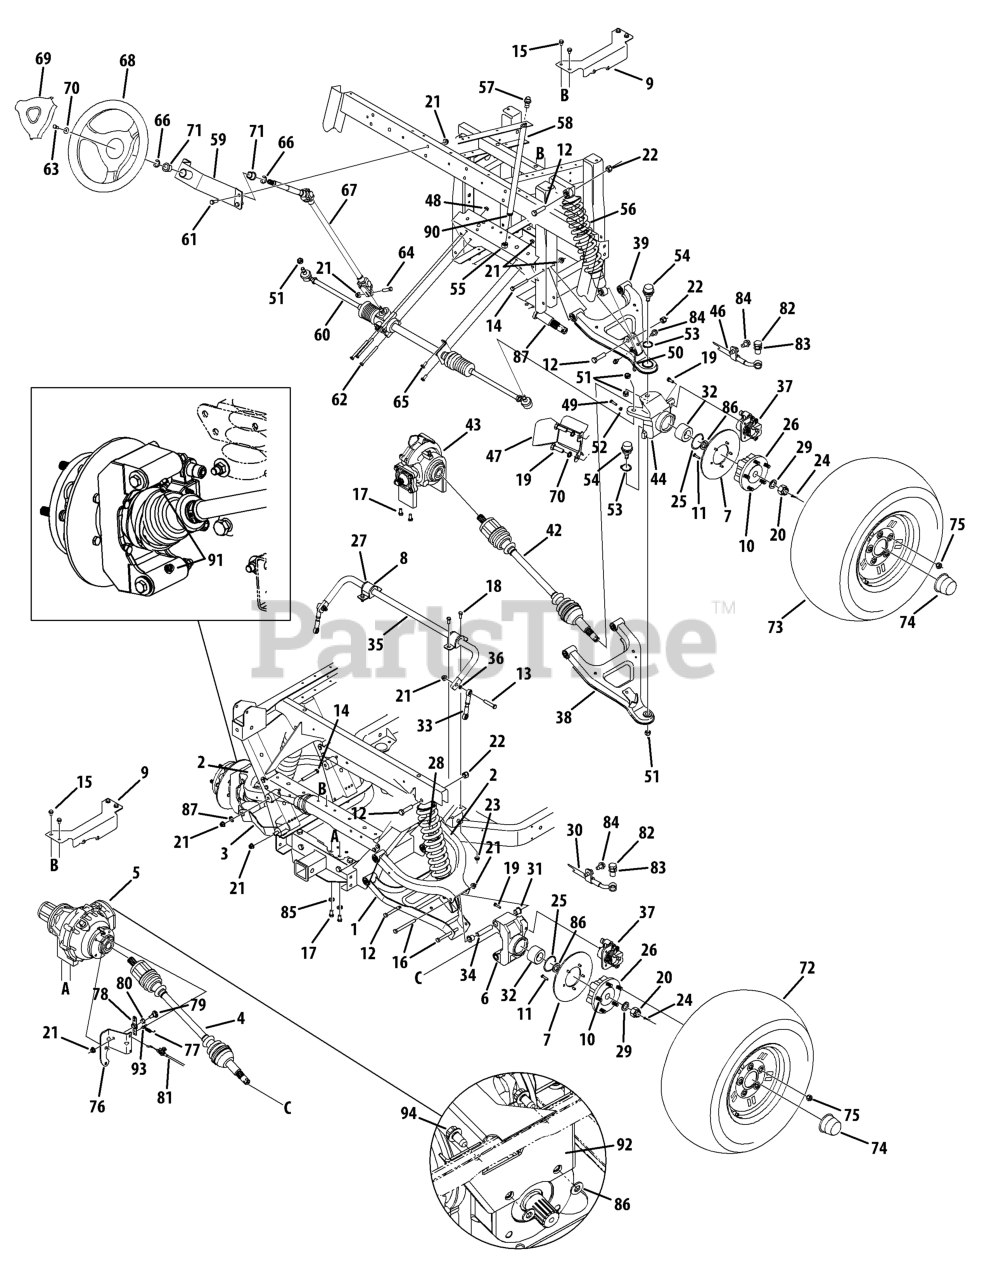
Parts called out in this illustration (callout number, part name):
1	Cont Assembly, lwr, r/rr
2	Cont Assembly, rr Upr
3	Cont Assembly, lwr, l/rr
4	Axle Assembly, cv Joint
5	Diff Assembly, Uv, complete
6	Hsg, rr, mach
7	Disc, brake, 8.00x.188
10	Stud, rib Neck, 7/16-14 X 1.6
11	Screw, 1/4-20, .625, gr5, lock
12	Screw, 1/2-13, 2.00, gr5, std
13	Screw, 3/8-18, 1.75, gr5
14	Screw, 3/8-16, 3.00, gr8, std
15	Scr, tt, 5/16-18, 0.500, hxindwsh
16	Screw, 3/8-16, 4.00, gr5
17	Screw, 3/8-16, .75, gr5, std
18	Screw, 5/16-24, .75, gr5, std
19	Screw, m8-1.25, 25.00
20	Nut, slotted, 22x1.5
21	Nut, flglk, 3/8-16, grf, nylon
22	Nut, hexlk, 1/2-13, grb, nylon
23	Nut, flglk, 5/16-18, grf, nylon
24	Pin, cot, 5/32, 1.25
25	Ring, ret, dho-60
26	Hub, Wheel
27	Bush, sway Bar
28	Shabs, 5.0 Stroke, rr
29	Wash, flat, .88 X 1.38 X .125, ht
30	Hose, brake, rear, right
31	Brg, flg, .625 X .750 X .750 Lg
32	Brg, dble Row, 60x30x37
33	Rod, cont, .375x3.886
34	Tube, pivot, rr/cont Arm
35	Bar, sway, rr
36	Washer, Flat, .407 x .812 x .135
37	Brake, hyd, caliper
38	Cont Assembly,r/frt,lwr
39	Arm Assembly,r/frt,upr
42	Axle Assembly,cv Joint,4x4
43	Diff Assembly,cfd,4x4
44	Hsg,knuckle,r/frt,mach
46	Hose, brake, front, right
48	Nut, Flg Lk, 5/16-18
49	Screw,1/4-20,1.00,gr5,spec
50	Wire, Brake Line
51	Nut,nylock,m12x1.25
52	Nut,hex,1/4-20,gr5
53	Ring,ret,34x1.6
54	B/jnt,bj14d-6201
55	Clamp,hose,.490 Dia.
56	Shabs,5.0 Stroke,frt
57	Vent,3/8 Dia
58	Hose,fuel Line
60	Steering Assembly
61	Screw,3/8-16,1.00,gr5,std
62	Screw,5/16-18,3.50,gr5,std
63	Screw,5/16-18,.75,gr5,patch
64	Screw,3/8-16,1.25,gr5,std
65	Screw,5/16-18,.75,gr5,std
66	Ring,e Type,.750
68	Wheel,strg,soft Grip 3 Spoke 5/8
69	Cvr,Wheel,steering Soft Grip
70	Wash,bell,.340 X .872 X .060
71	Brg,flg,.754id X 1.00odx.925
72	Wheel Ass’y, r/compl,25x11-12
72	Wheel Ass’y, compl,25x10-12
72	Wheel Ass’y, compl,25x10-12, Turf
72	Tire Only, 25x11-12
72	Tire Only, 25x10.5-12
73	Wheel Ass’y, r/compl,25x10-12
73	Wheel Ass’y, compl,25x10-12
73	Wheel Ass’y, compl,25x10-12, Turf
73	Tire Only, 25x10-12
73	Tire Only, 25x10.5-12
74	Cap, Wheel UV
74	Cap, Wheel UV, Chrome
75	Nut, lug, 7/16-14
75	Nut, lug, 7/16-14, Chrome
77	Spr, ext, .38od x 2.10
78	Lvr, Ass’y, Diff Lock
79	Scr, shldr, .500 dia x .434
80	Brg, flg, nyliner, .500id x .34lg
81	Cbl, cont, diff, lock
82	Ftg, banjo ftg bolt, M10x1.00
83	Ftg, banjo ftg crush wash,10mm
84	Screw, tt, 1/4-20x.500
85	Washer, Flat, .385 x .870 x .092
86	Wash, Flat, .344 x .688 x .065
87	Axle, Frt, 4x2
90	Clamp, Hose, Adj.
94	Scr., tt, 3/8-16 x .750
